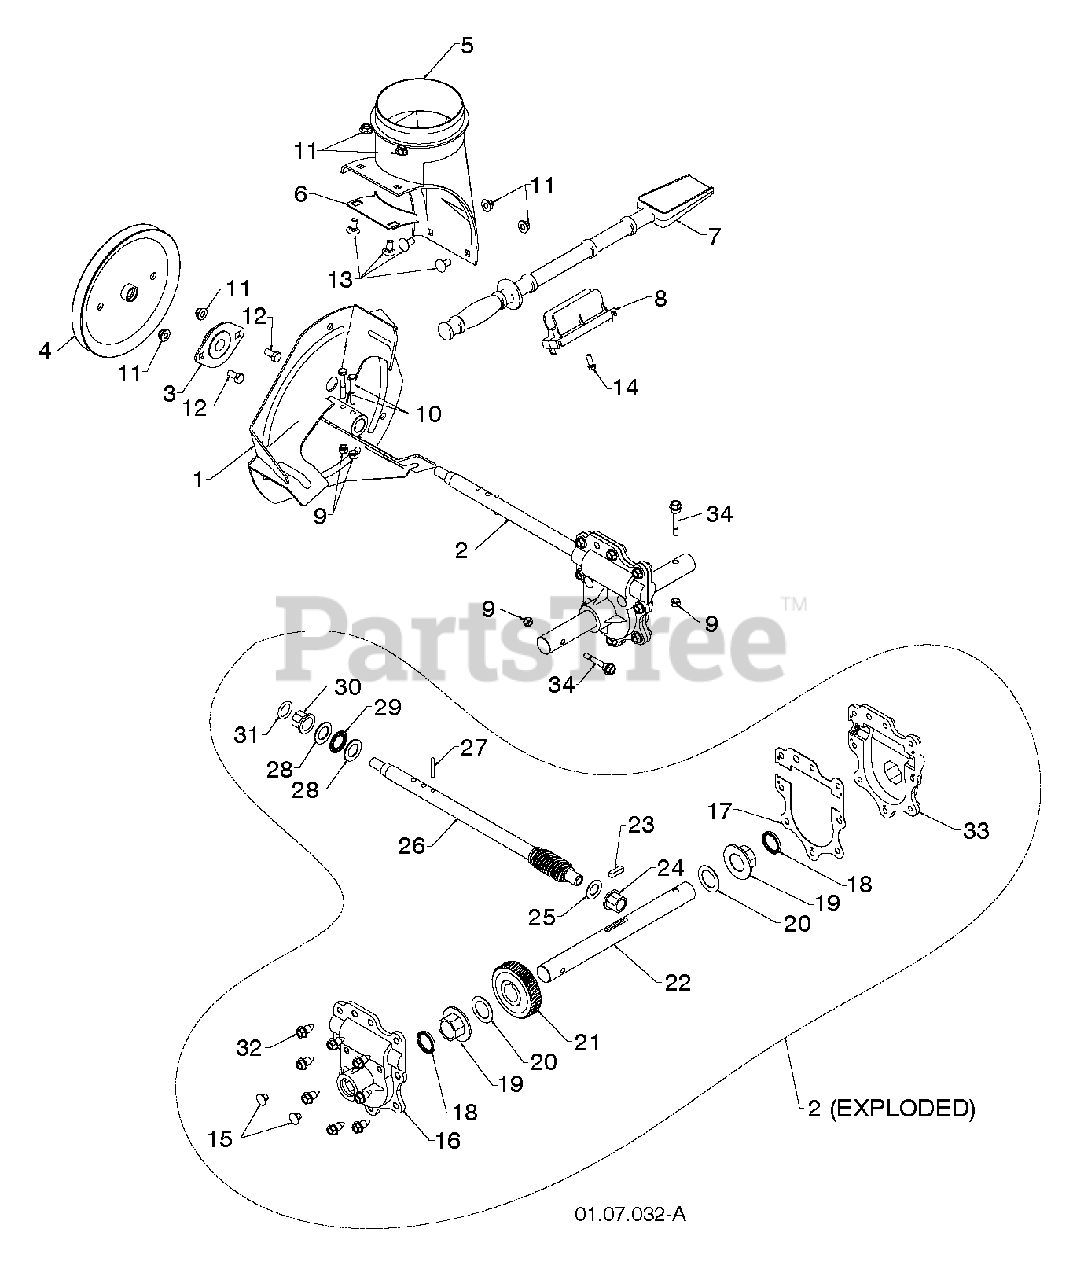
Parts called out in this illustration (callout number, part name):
1	IMPELLER ASSY
2	GEARBOX.AUGER.SCREW.ON.PULLEY
3	BEARING FLANGE
4	PULLEY.IMPELLER.7.5IN.SCREW.ON
5	BASE.DISCHARGE.CHUTE
6	BRACKET, CORNER DISCHARGE
7	CLEAN OUT TOOL
8	CLIP.CLEANOUT.TOOL
9	LOCKNUT.NYLOC.1/4-20
10	SCREW.HEX.HD1/4-20X
11	NUTNYLOK.FLRANGE.5/16-18
12	BOLT, HEX HEAD 5/16-18
13	BOLT.CARRIAGE.5/16-18X
14	SCREW.HWH.13-16-5.8.BZP
15	CASE PLUG
16	GEAR.BOX.COVER.RIGHT.SIDE
17	GASKET.GEAR.BOX
18	OIL SEAL
19	FLANGE BUSHING-1"
20	WASHER TRUST 1"
21	WORMGEAR.AUGER.SNOW
22	AUGER SHAFT
23	KEY, SQUARE 1/4 X .875
24	FLANGE BUSHING-5/8
25	WASHER, THRUST 5/8
26	SHAFT INOUT 1/2-20
27	PIN, ROLL 3/16 X 1-1/8
28	WASHER, THRUST 3/4
29	BEARING TRUST 3/4 NTA-1220
30	BUSHING, FLANGE 3/4
32	BEARING TRUST 3/4 NTA-1220
32	HEX SCREW-5/16 X 3/4
33	GEAR.BOX.COVER.LEFT.SIDE
34	BOLT.SHOULDER.SHEAR.1/4-20.
